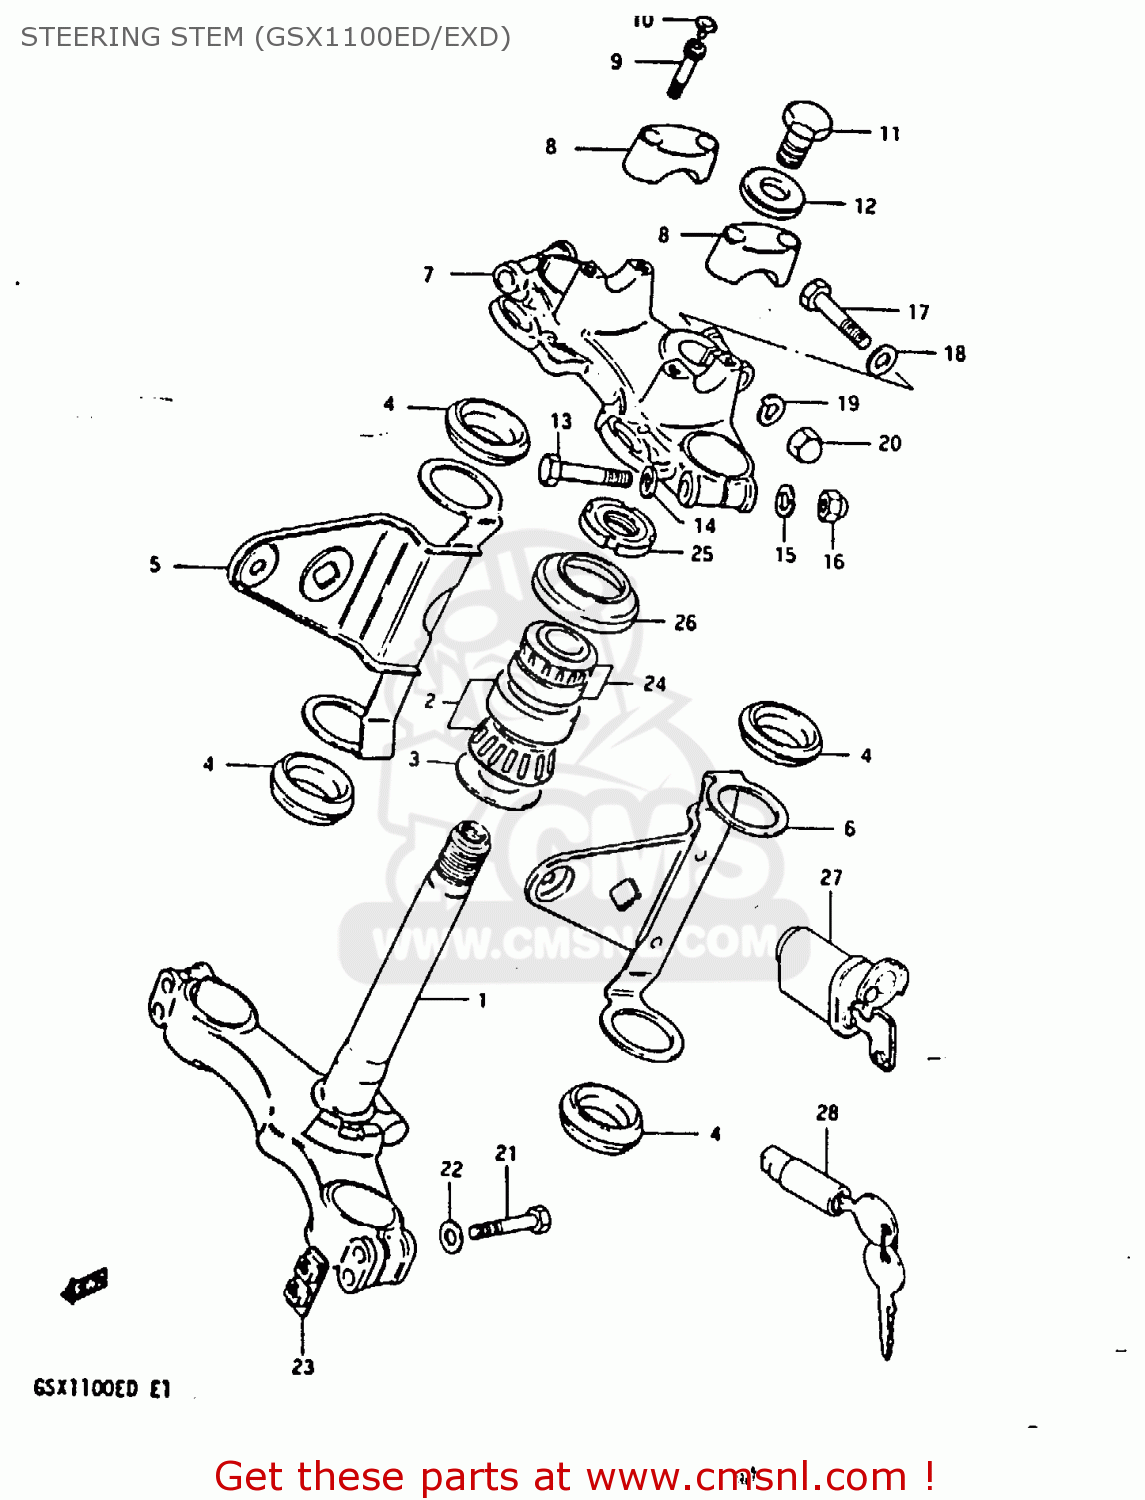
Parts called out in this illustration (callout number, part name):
1	STEM,STEERING
2	BEARING
3	WASHER,THRUST
4	CUSHION,HEADLAMP BRACKET
5	BRACKET, HEAD LAMP RH
6	BRACKET, HEAD LAMP LH
7	HEAD,STEERING STEM
8	HOLDER,HANDLEBAR
9	BOLT
10	CAP(OD:14.5)
11	NUT,STEM HEAD
12	WASHER,STEERING STEM B
13	BOLT 10X55
14	WASHER
15	LOCK WASHER
16	NUT, LOWER LH
17	BOLT 8X50
18	WASHER
19	LOCK WASHER
20	NUT
21	BOLT 8X55
22	WASHER
23	NUT,FR FORK INNER TUBE
24	TAPER,ROLLER BEARING
25	NUT,STEERING STEM
26	DUST SEAL,STEERING UPR
